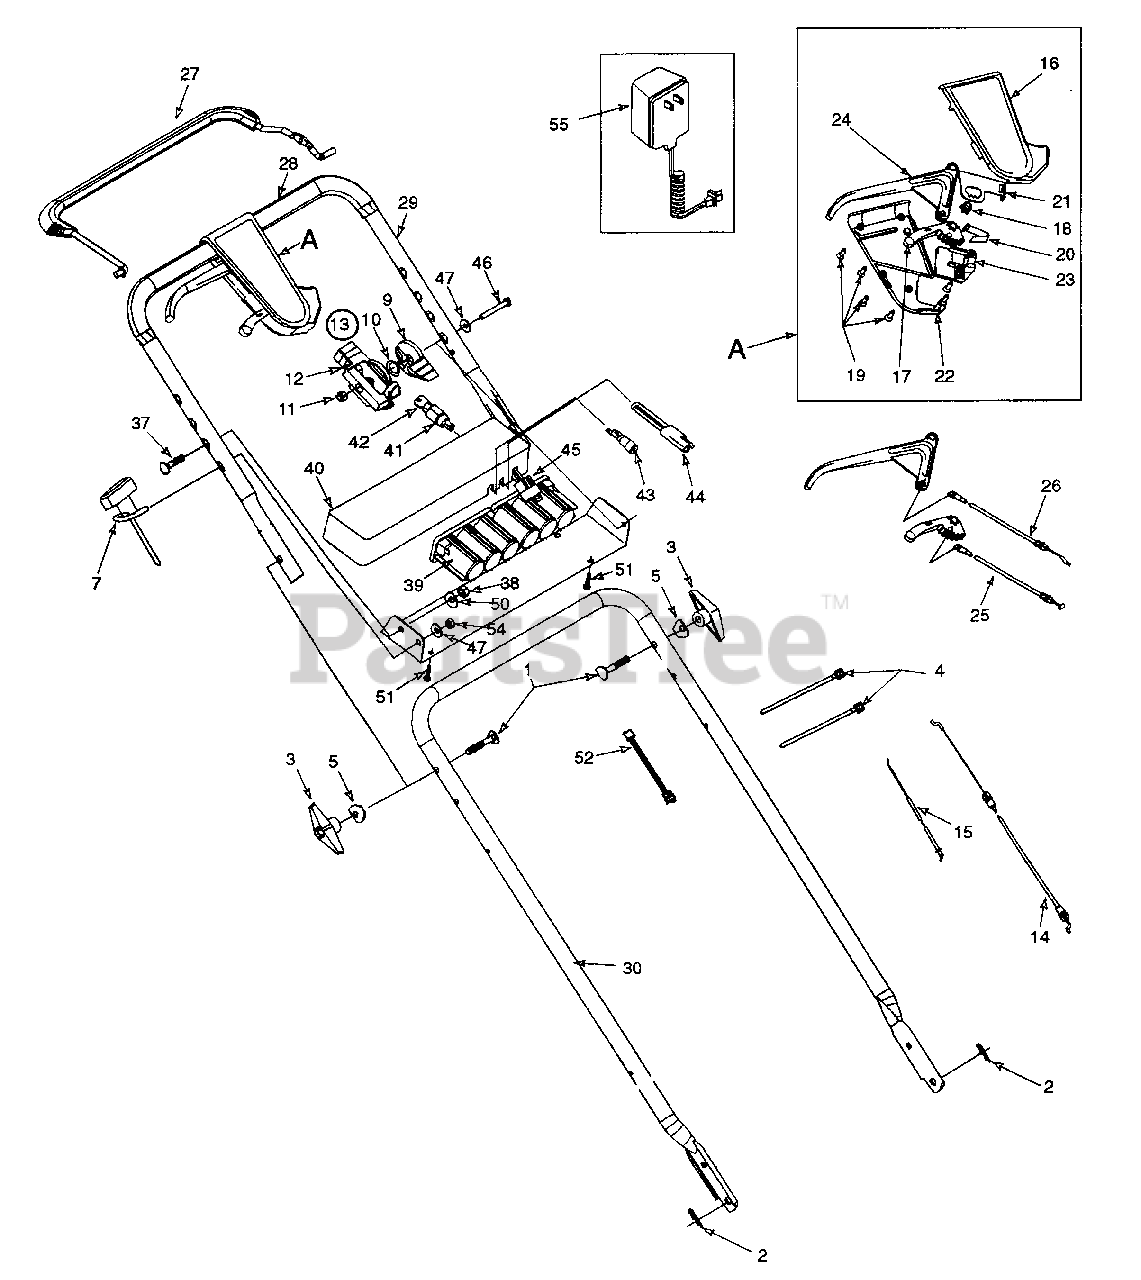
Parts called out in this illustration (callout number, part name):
1	Bolt Cur Carr. 5/16-18 x 2" Lg.
2	Cotter Pin .072 x 1.12 Lg.
3	Knob Ass'y Wingnut 5/16-18
4	Strap 4.3 Lg.
5	Wash. Sad. .320 ID x .830 OD
7	Rope Guide Eyebolt
9	Throttle Lever
10	Spring Wash. Curved
11	Nut 1/4-20 Top locknut Insert
12	Housing, Throttle
13	Throttle Control
14	Control Cable 44" Lg.
15	Cable Throttle 60" Lg.
16	Upper Control Housing
17	6 Speed Shift Lever
18	Gear Insert
19	C Sunk Tap Screw #10 x .75 L
20	Shift Lever Spring
21	6 Spd. Rack Cable Brkt.
22	Lower Control Housing
23	Cable Mounting Cap
24	Control Lever
25	6 Spd. Cable
26	S.P. Cable
27	Control Handle
28	Foam Grip
37	Cur. Carr. Bolt 5/16-18 x 1" Lg.
38	Hex Nut 5/16-18 Thd.
39	Battery Pack - 12 Volt
40	Battery Tray
41	Ignition Switch
42	Ignition Key
43	Fuse Holder
44	Plug
45	Wire Harness
46	Hex Bolt 1/4-20 x 2" Lg.
47	Bell Wash 1/4" I.D.
51	Truss Mch. Tap Scr. 1" Lg.
52	Harness Ext.
54	Hex Nut 1/4-20
55	Battery Charger
